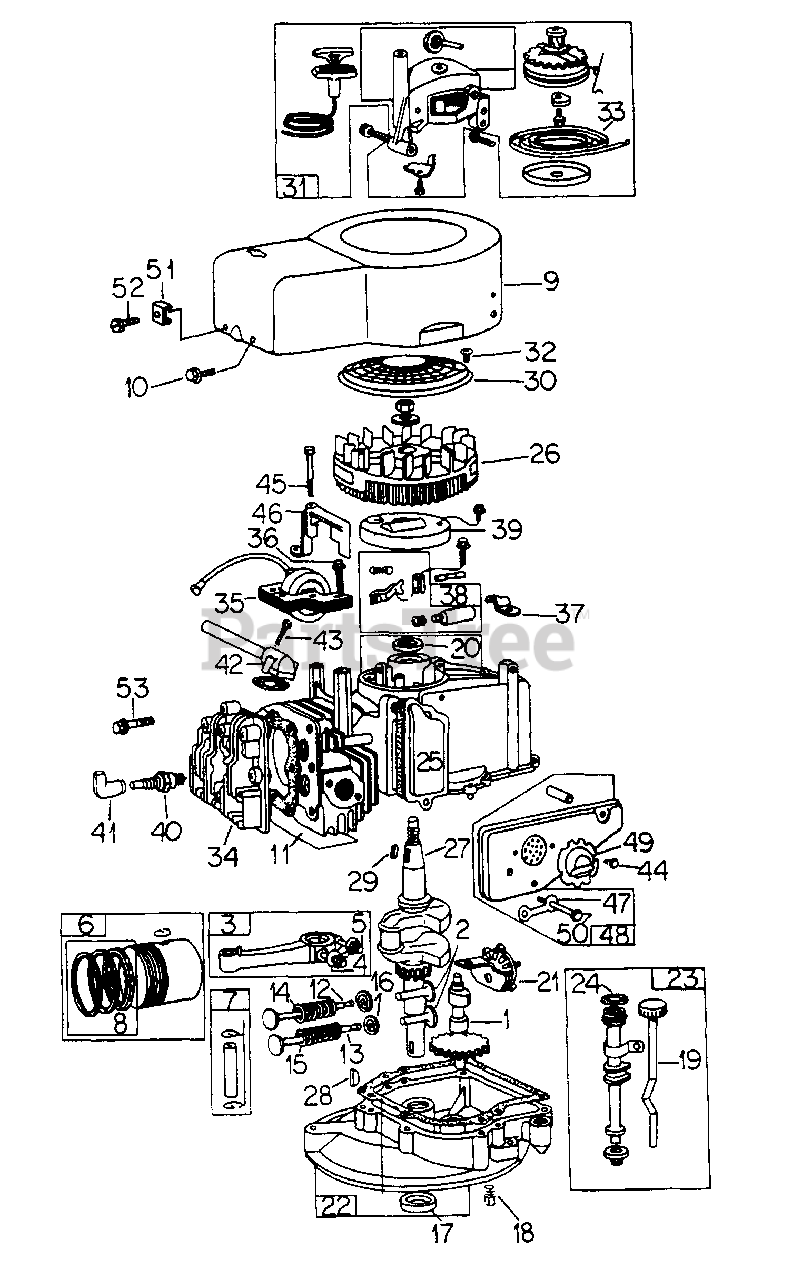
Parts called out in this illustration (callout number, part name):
2	TAPPET, VALVE
3	ROD ASSY, CONNECTING STANDARD
4	LOCK, SCREW HEAD
5	SCREW, CONNECTING ROD
6	PISTON ASSY, STANDARD
7	PIN, PISTON & RETAINER - STD
8	RING SET, PISTON - STANDARD
9	HOUSING, BLOWER
10	SCREW, BLOWER HOUSING
11	SHIELD, CYLINDER
12	VALVE, INTAKE
13	VALVE, EXHAUST
14	SPRING, INTAKE VALVE
15	SPRING, EXHAUST VALVE
16	RETAINER, VALVE SPRING
17	SEAL, OIL
18	PLUG, 3/8-18 AUTO, SQ-HD GAL DRAIN
20	SEAL, OIL
21	SLINGER, OIL GEAR BRACKET
23	FILLER, OIL
24	RING, OIL FILLER CAP
25	BREATHER, VALVE CHAMBER
26	FLYWHEEL, MAGNETO
28	KEY, CRANKSHAFT
29	KEY, FLYWHEEL
30	SCREEN, ROTATING
31	STARTER, VERTICAL PULL
32	SCREW, SCREEN MOUNTING
33	SPRING, VERTICAL PULL STARTER
34	HEAD, CYLINDER
35	ARMATURE, MAGNETO
36	SCREW, ARMATURE MOUNTING
37	CLAMP, CONDENSER
38	POINTS AND CONDENSER
39	COVER, BREAKER POINT
40	PLUG, SPARK (CHAMPION)
41	ELBOW, SPARK PLUG INSULATOR
42	TUBE, FUEL INTAKE
43	SCREW, INTAKE ELBOW MOUNTING
44	SCREW, MUFFLER DEFLECTOR
46	BLADE, GOVERNOR
47	LOCK, MUFFLER SCREW
48	MUFFLER ASSY, EXHAUST
49	DEFLECTOR, MUFFLER
50	SCREW, MUFFLER MOUNTING
51	CLAMP, CASING
52	SCREW W/LOCKWASHER, HEX-HD
53	BOLT, CYLINDER HEAD
